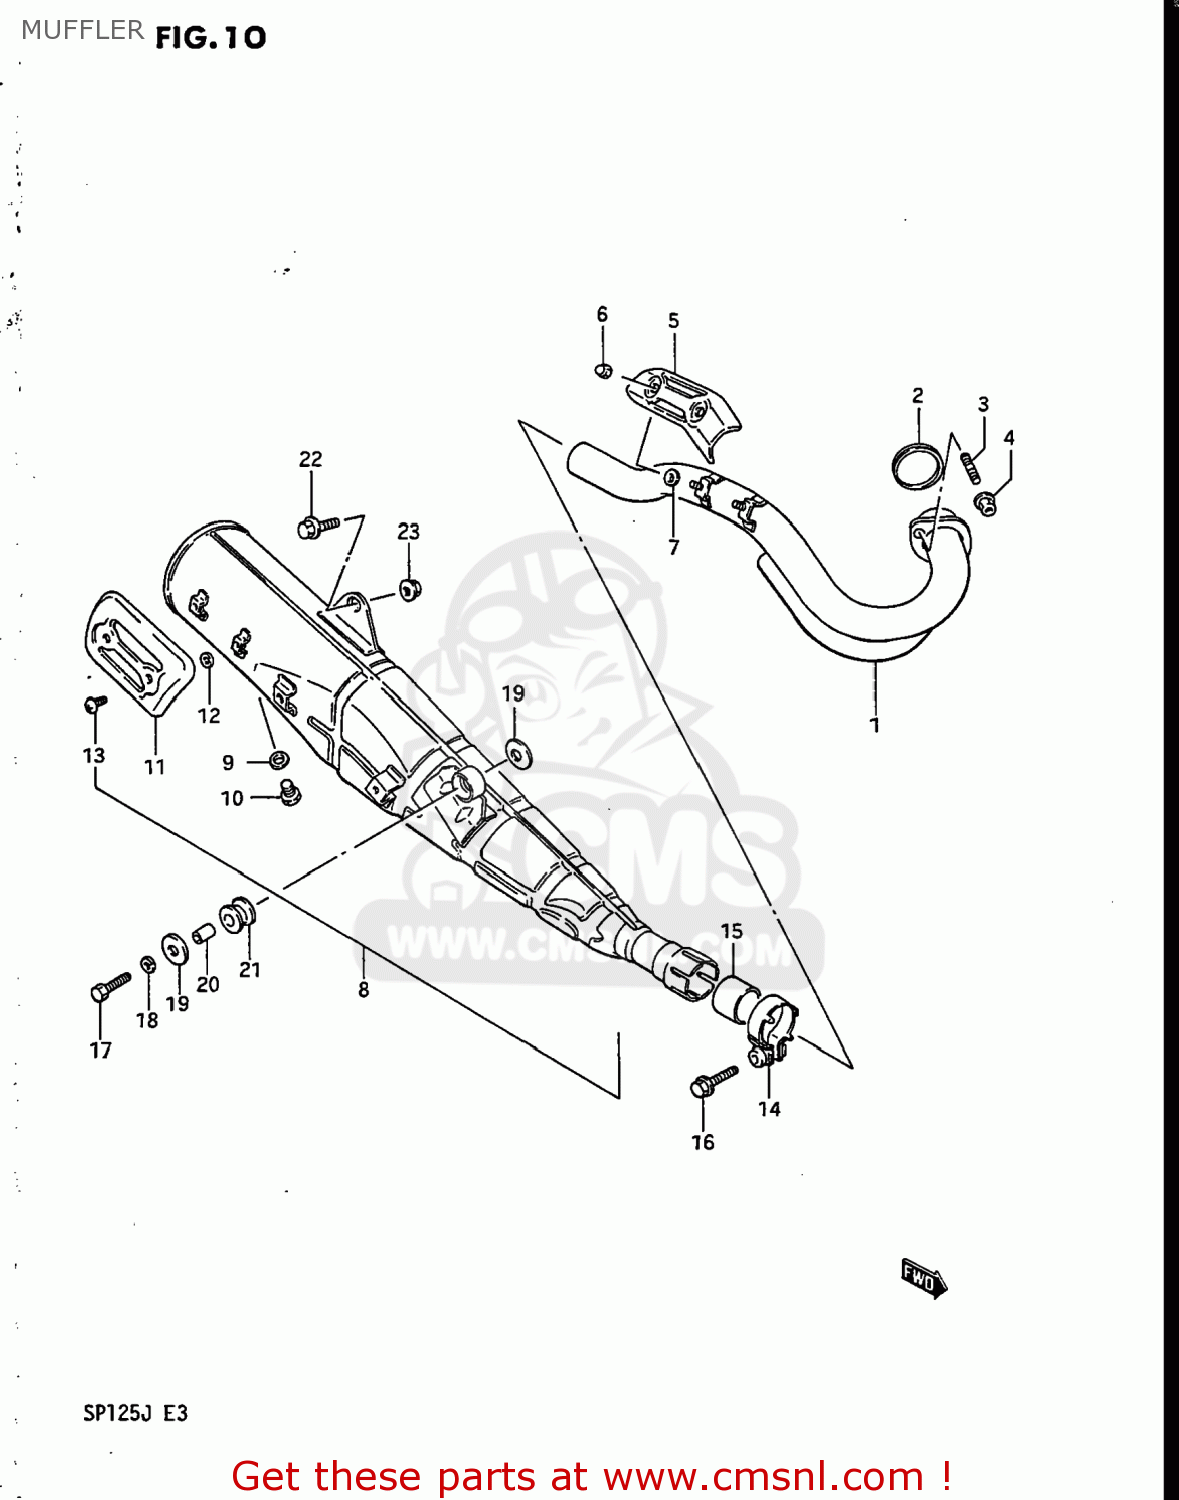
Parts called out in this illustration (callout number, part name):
1	PIPE,EXHAUST
2	GASKET,EXHAUST PIPE (NAS)
3	BOLT,STUD
4	NUT
5	COVER,EXHAUST PIPE
6	NUT (6MM)
7	GASKET (NAS)
8	MUFFLER ASSEMBLY
9	GASKET(12.1X16.2X3.7) (NAS)
10	PLUG(12X9)
11	COVER,MUFFLER
12	GASKET (NAS)
13	SCREW
14	CLAMP,MUFFLER CONNECTOR
15	CONNECTOR,MUFFLER
16	BOLT
17	BOLT
18	WASHER,LOCK,8.
19	WASHER (8.5X20X1.6)
20	SPACER (8.6X12X17.5)
21	CUSHION
22	BOLT(8X25)
23	NUT
